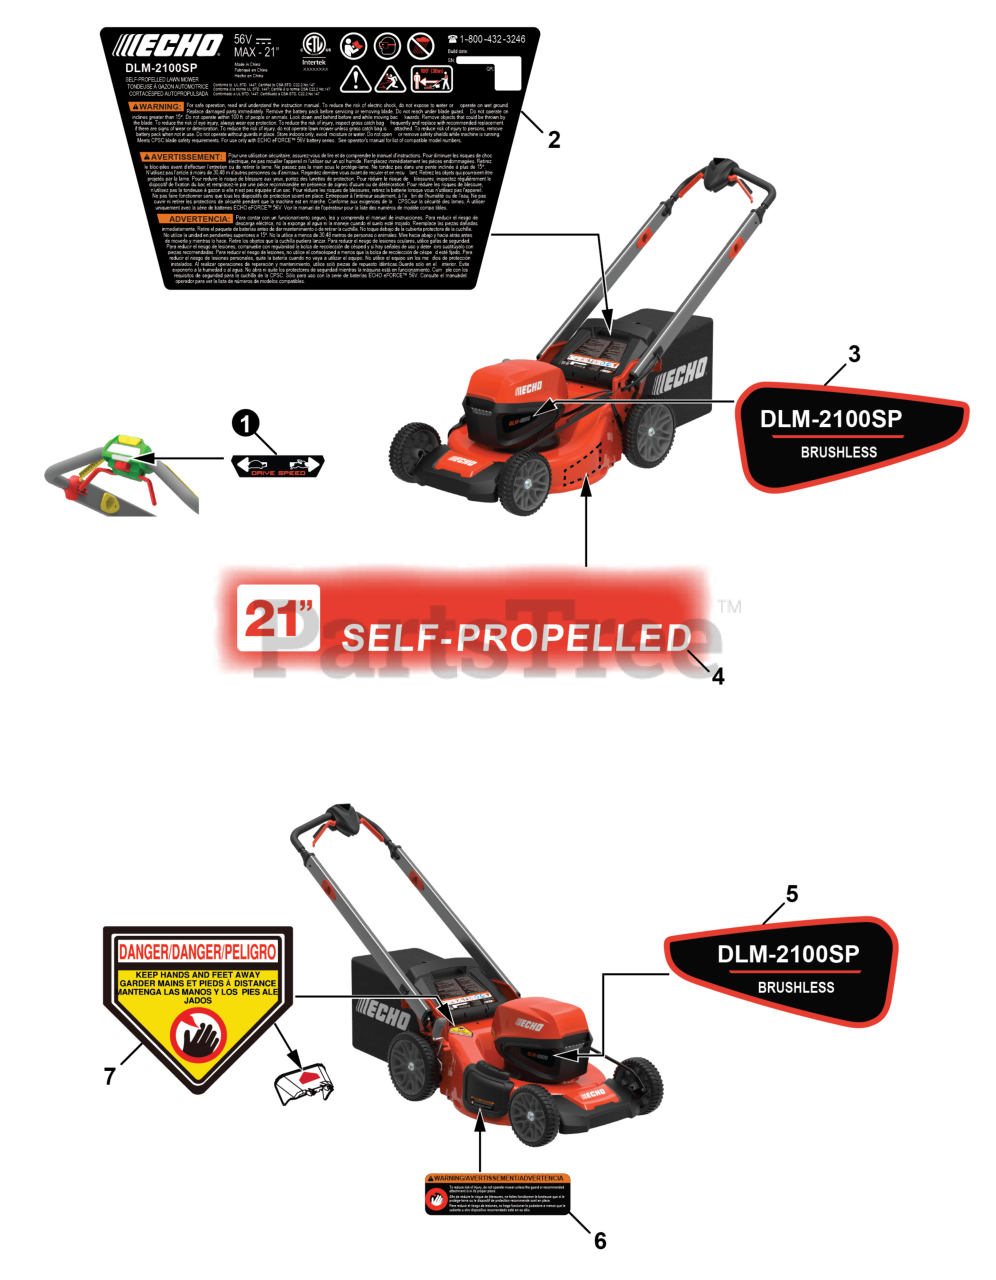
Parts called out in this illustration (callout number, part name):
1	LABEL,ADJUSTING
3	BRAND LOGO,LEFT DECK
4	LOGO,21" SELF-PROPELLED
5	BRAND LOGO,RIGHT DECK
6	LABEL,SIDE WARNING
7	LABEL,WARNING
